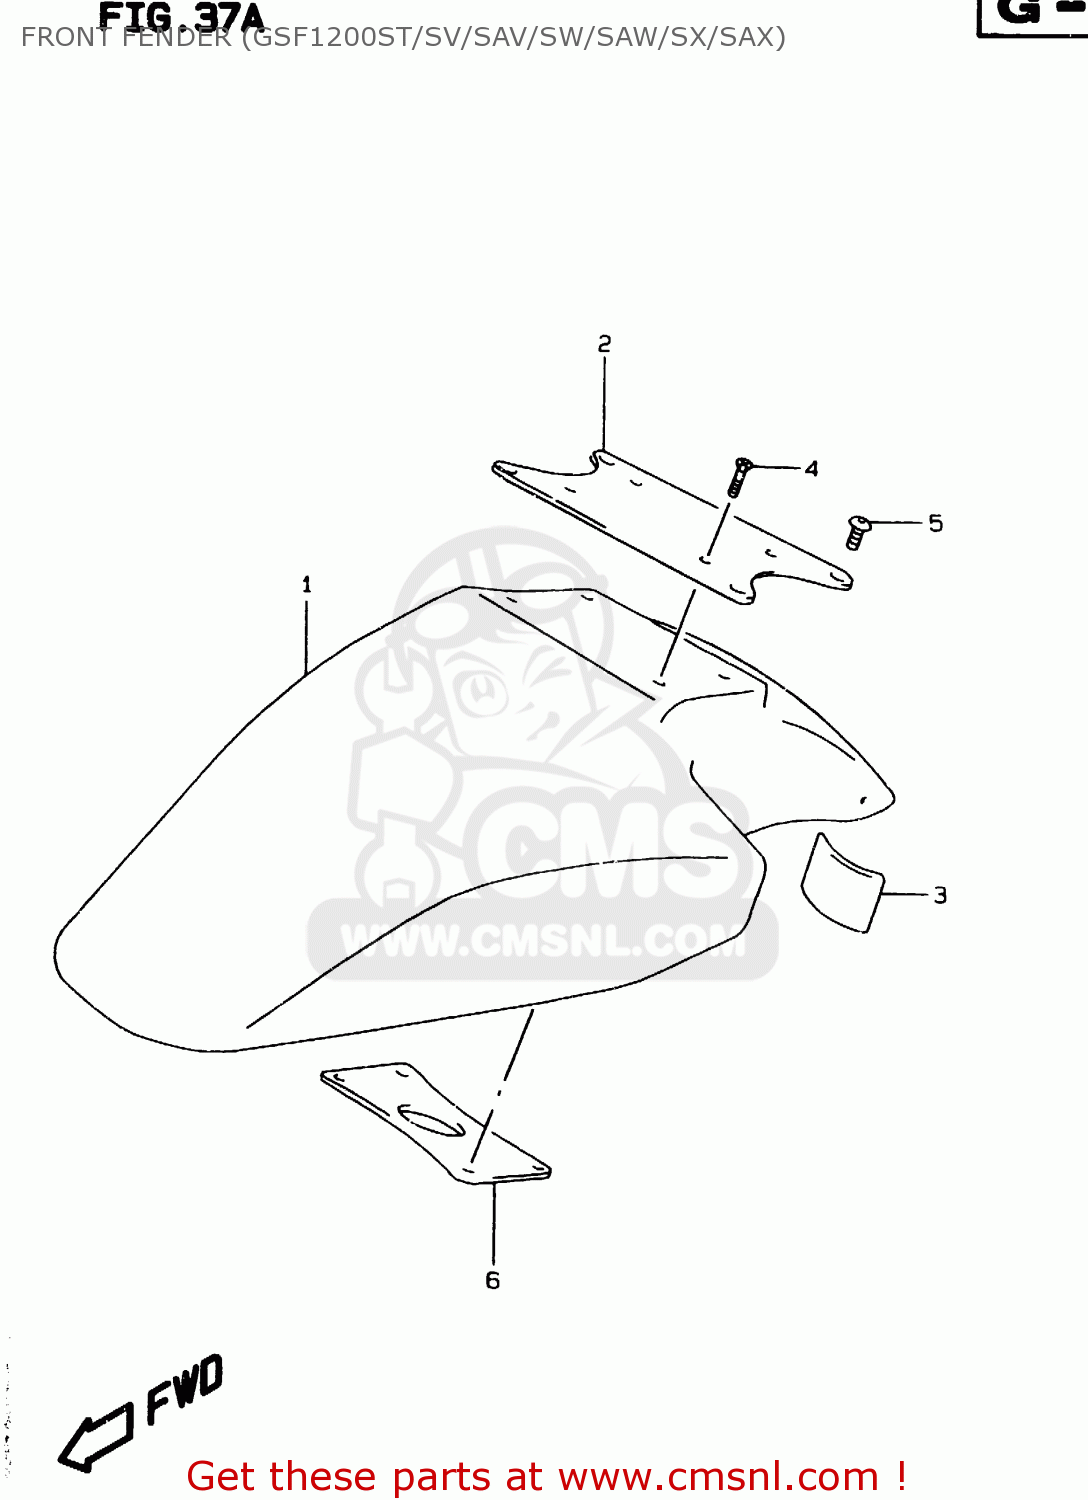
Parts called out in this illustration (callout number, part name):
1	FENDER,FR
2	BRACE,FR FENDER
3	CUSHION,FR FENDER
4	SCREW(5X18)
5	SCREW(8X16)
6	BRACE,FR FENDER INNER
